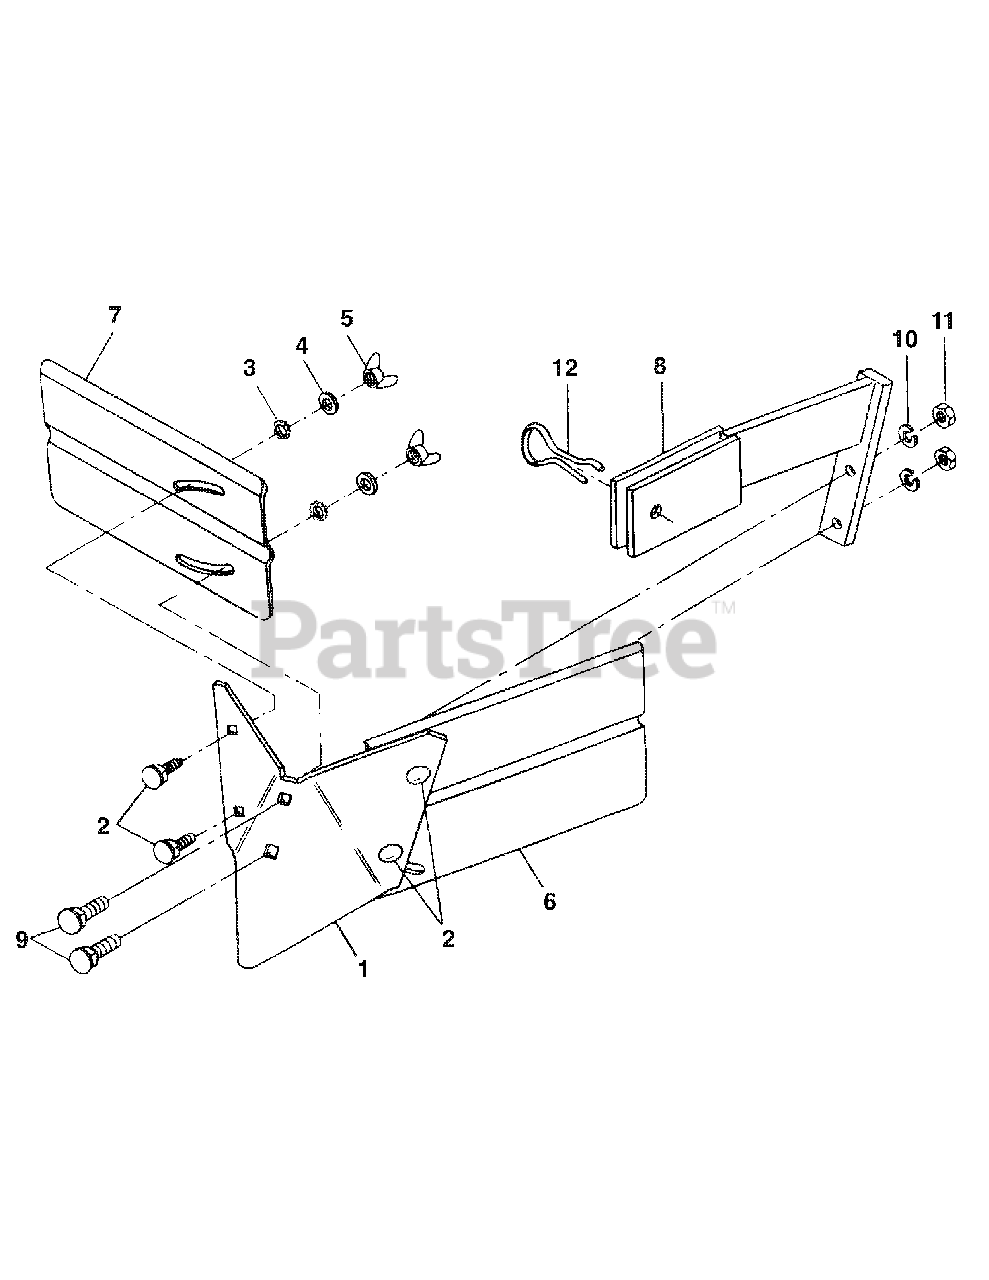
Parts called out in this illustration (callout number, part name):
1	Furrower Blade
2	Carriage Bolt, 5/16-18 x 3/4
3	Star Washer, External Tooth, 5/16
4	Plain Washer, 5/16 S.A.E
5	Wing Nut, 5/16-18
6	Hiller Wing, left
7	Hiller Wing, right
8	Blade Mounting Bracket
9	Carriage Bolt, 3/8-16 x 1-1/2
10	Lockwasher, 3/8, plated
11	Hex Nut, 3/8-16, plated
12	Clinch Pin
